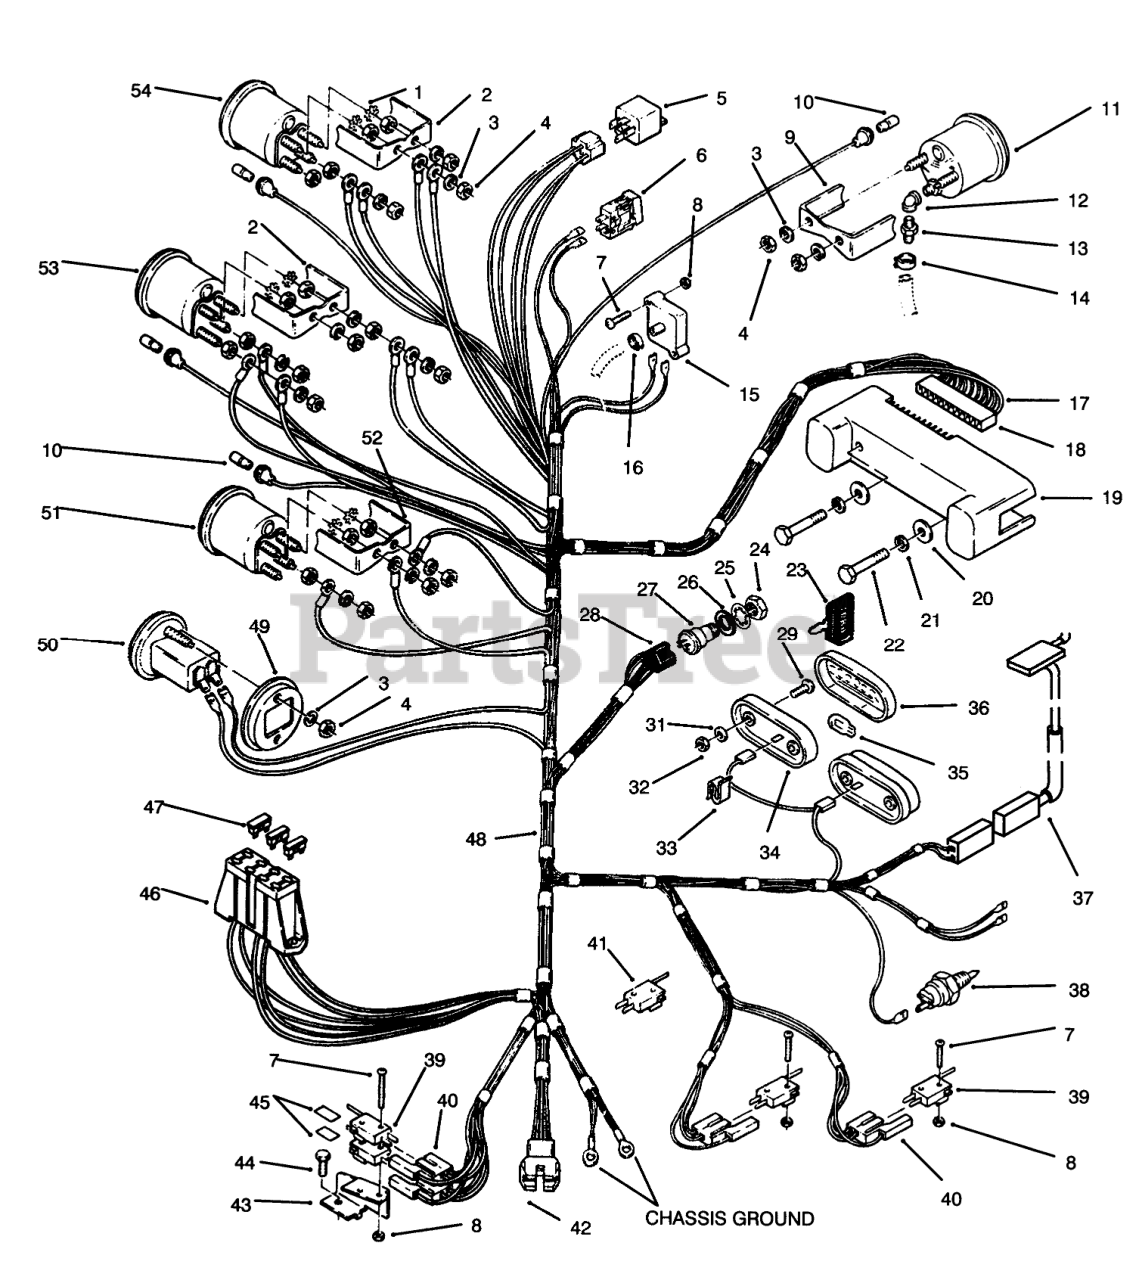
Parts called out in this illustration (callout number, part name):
1	WASHER-LOCK
2	CLAMP-MOUNTING
3	WASHER-LOCK
4	NUT-HEX
5	RELAY
6	Light Switch
7	Screw
8	NUT HEX 4-40 ELAST
9	Bracket-Mounting
10	LAMP-MINIATURE GE 53X
11	Gauge-Vacuum (Incl. Ref. #3-4 & 9)
12	ELBOW
13	FITTING STRAIGHT
14	Clamp
15	SENSOR-AIR CLEANER
16	CLAMP-HOSE 5/16"
17	Terminal
18	Connector-Male
19	CIRCUIT-BRD 8 LIGHT
20	WASHER-FLAT
21	WASHER-LOCK
22	SCREW
23	KEY-IGNITION
25	LOCKWASHER
26	Washer
27	Switch-Ignition(Incl. Ref. #24-26)
28	CONNECTOR-5 WAY-SERV
29	Screw
31	WASHER-LOCK, INT
32	NUT-HEX
33	SPEED CLIP
34	BASE-TAIL LIGHT
35	LIGHT BULB
36	LENS-TAIL LIGHT
37	SWITCH-SEAT
38	SENSOR-HYDRO OIL HOT
39	SWITCH
40	CONNECTOR BODY
41	SWITCH - CLUTCH
42	9-CIRCUIT CAP
43	Support-Switch
44	Bolt
45	BARRIER - SWITCH
46	FUSE-HOLDER 4 WAY
47	FUSE-10 AMP
48	WIRING-HARNESS & DIA
49	Bracket-Mountin
50	Hourmeter (Incl. Ref. #3-4 & 49)
51	Tachometer (Incl. Ref. #1, 3-4 & 52)
52	MOUNTING-BRACKET
53	Gauge-Fuel (Incl. Ref. #1-4)
54	Voltmeter (Incl. Ref. #1-4)
